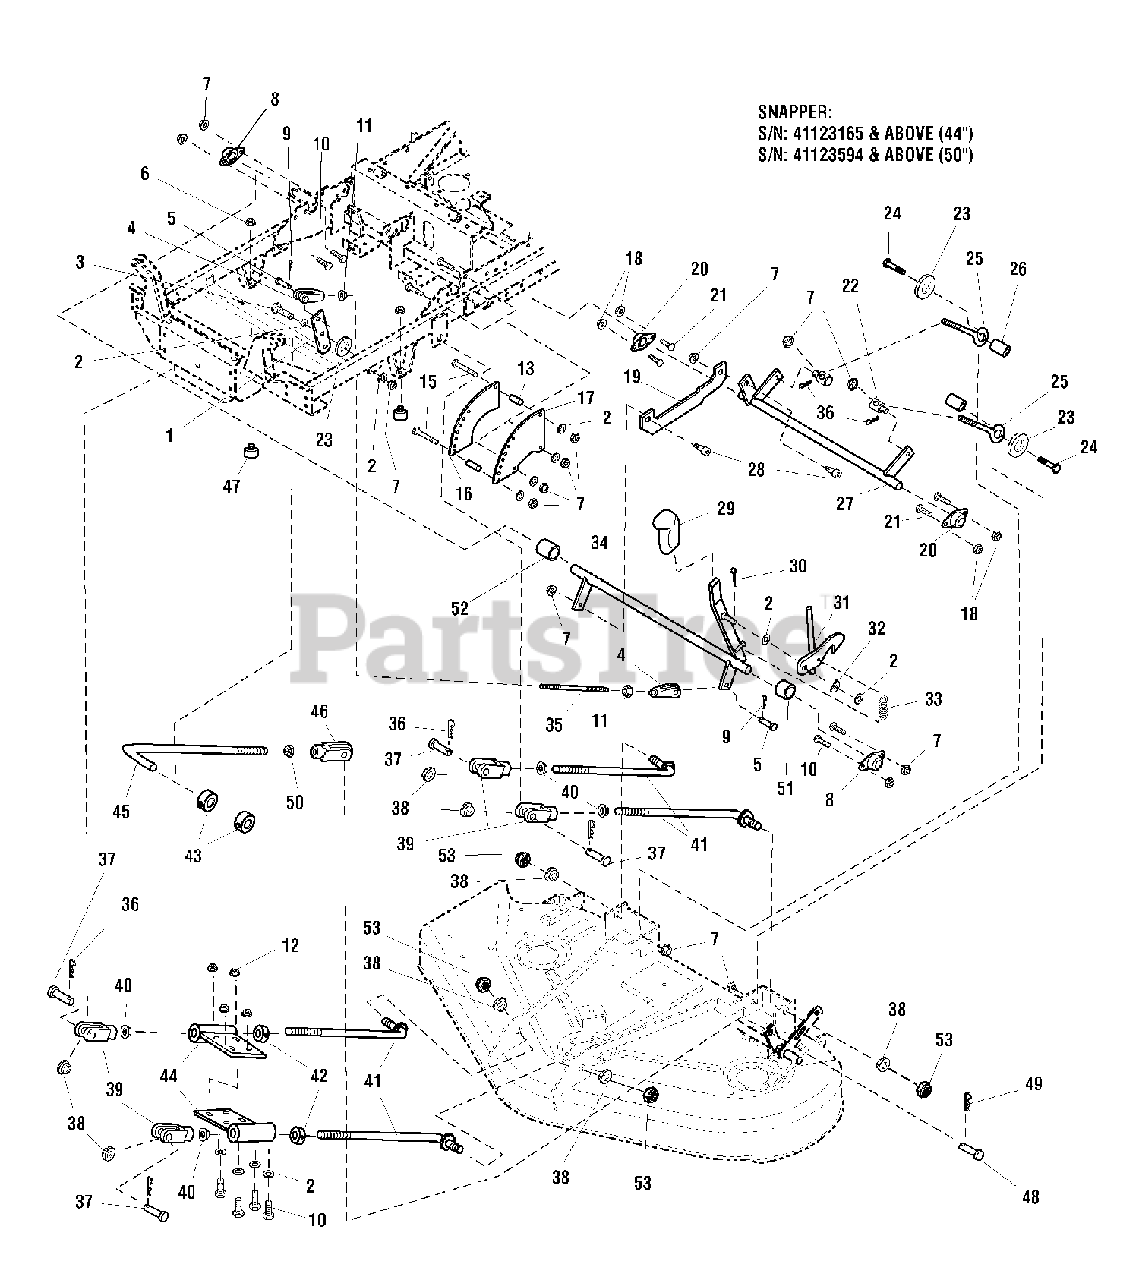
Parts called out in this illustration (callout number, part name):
1	* REVERSING LINK
2	WASHER, 3/8, SAE
3	BOLT, 3/8-16 X 1-1/2" GD5 CZ
6	HEX NUT, SERRATED FLANGE, 1/4-20
7	NUT, HEX NYLON LOCK, 3/8-16
8	BRONZE FLANGE BEARING, 3/4"
9	* COTTER PIN
10	BOLT, 3/8-16 X 3/4" GD5 CZ
12	HEX NUT, SERRATED FLANGE, 3/8-16
13	SPACER
15	BOLT, 3/8-16 X 2-1/2" GD5 CZ
16	DECK HEIGHT PLATE, INNER
17	DECK HEIGHT PLATE,OUTER
18	HEX NUT, NYLON LOC, 5/16-18
19	DECK LIFT LINK
20	BRONZE FLANGE BUSHING
21	BOLT, 5/16-18 X 3/4 GD5
22	ADJUSTER, BRAKE LINKAGE
23	WASHER, 1-3/4 OD X .390 ID
24	BOLT, 3/8-16 X 2-1/4" GD5 CZ
25	EYE BOLT, 3/8-16
26	SPACER
27	REAR DECK LIFT SHAFT
28	BOLT, 1/2" X 3/8" SHOULDER
29	HANDLE COVER
30	COTTER PIN, 3/16 X 1-1/2
31	DECK LOCK
32	SPRING WASHER, 3/8
33	EXTENSION SPRING
34	DECK HEIGHT SHAFT
36	HAIRPIN
37	PIN, CLEVIS, 1/2 X 1-1/2
38	SUPPORT BUSHING
39	CLEVIS, 1/2-20
40	HEX JAM NUT, 1/2-20
41	DECK HANGER ROD
42	SPLIT COLLAR, 1/2"
44	DECK STABILIZER
45	* ROLLER CONNECTING ROD (44" DECK)
47	RUBBER BUMPER, 1/4-20
49	* HAIRPIN
51	SPACER, .76 X 1.00 X .50
52	SPACER, .76 X 1.00 X 1.00
53	NUT, Hex, Nylon Lock, 1/2-20
